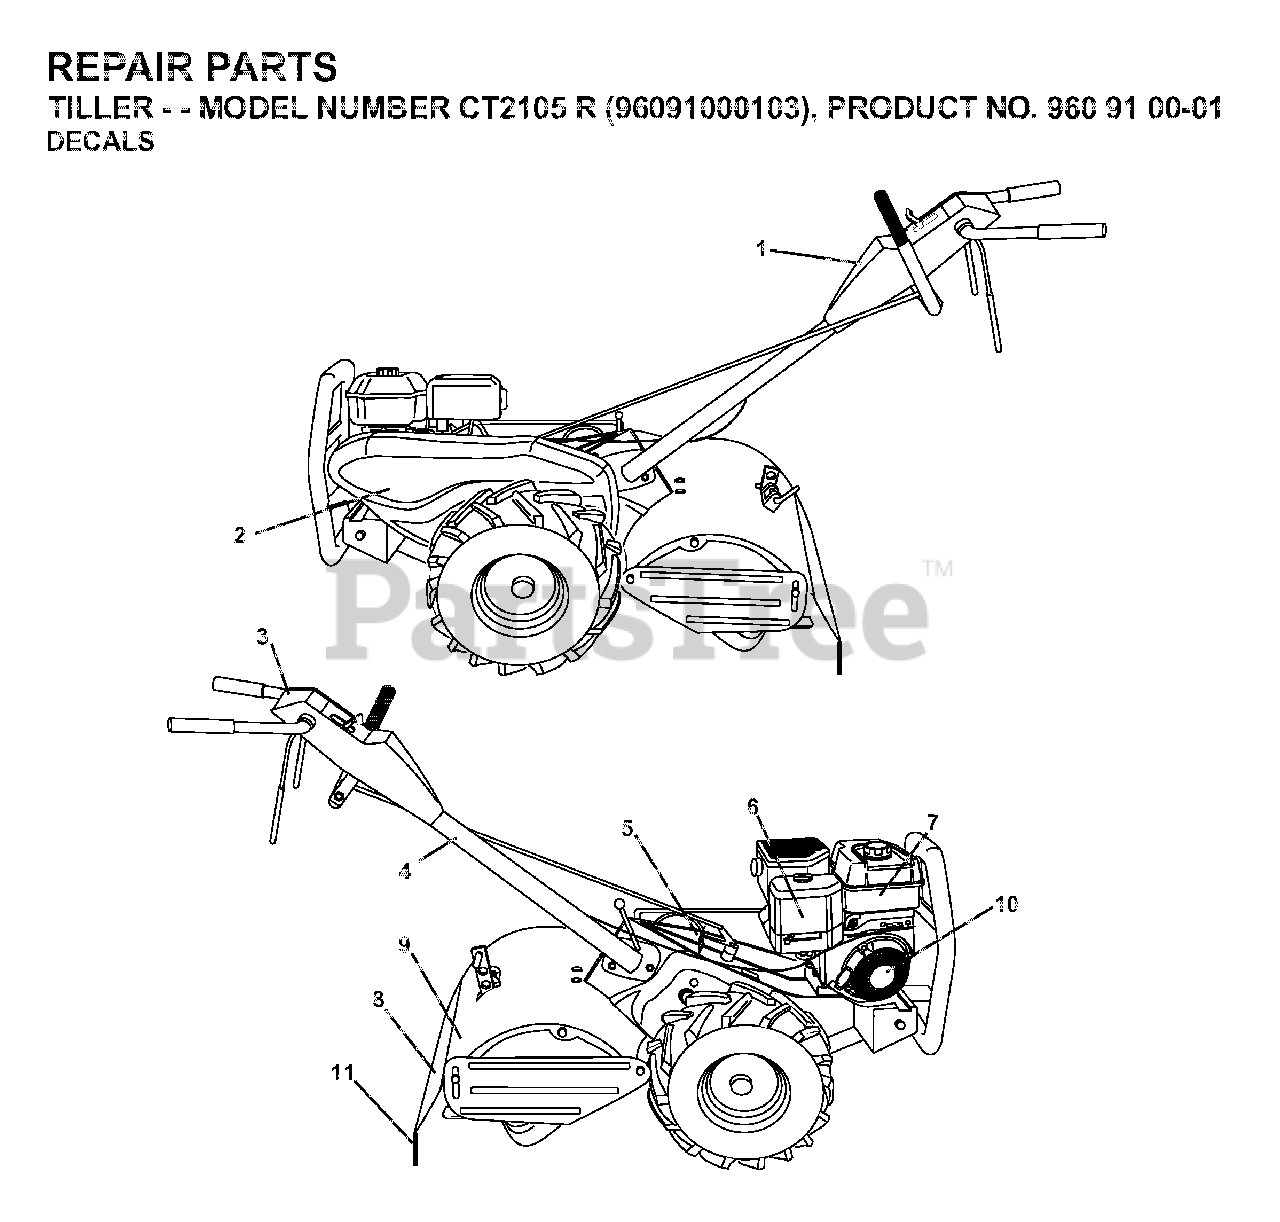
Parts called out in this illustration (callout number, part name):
5	DECAL.SHIFT.INDICATOR.TILLER
9	DECAL EUROPE STANDARD CE
10	DECAL.REWIND
